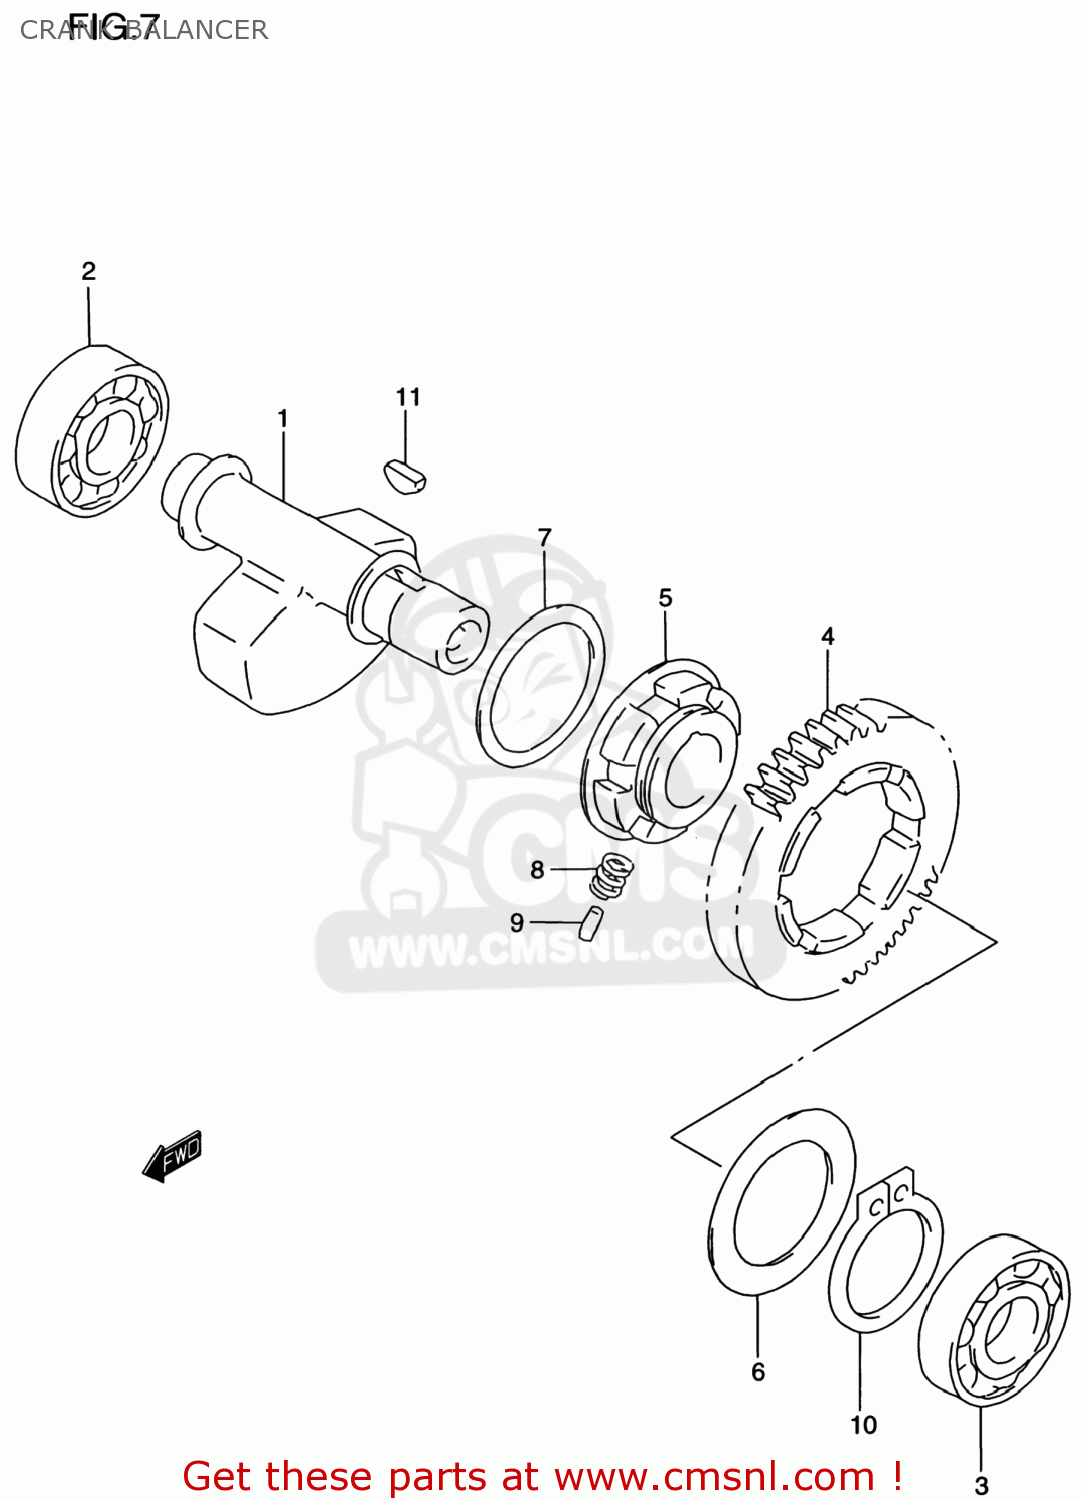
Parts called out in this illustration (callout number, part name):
1	BALANCER,CRANK
2	BEARING(22X56X16)
3	BEARING(20X47X14)
4	GEAR,CRANK BAL DRIVEN(NT:43)
5	RACE,CRK BAL DRIVEN GR INNER
6	WASHER
7	WASHER
8	SPRING
9	PIN(4.5X9.5)
10	CIRCLIP
11	KEY
